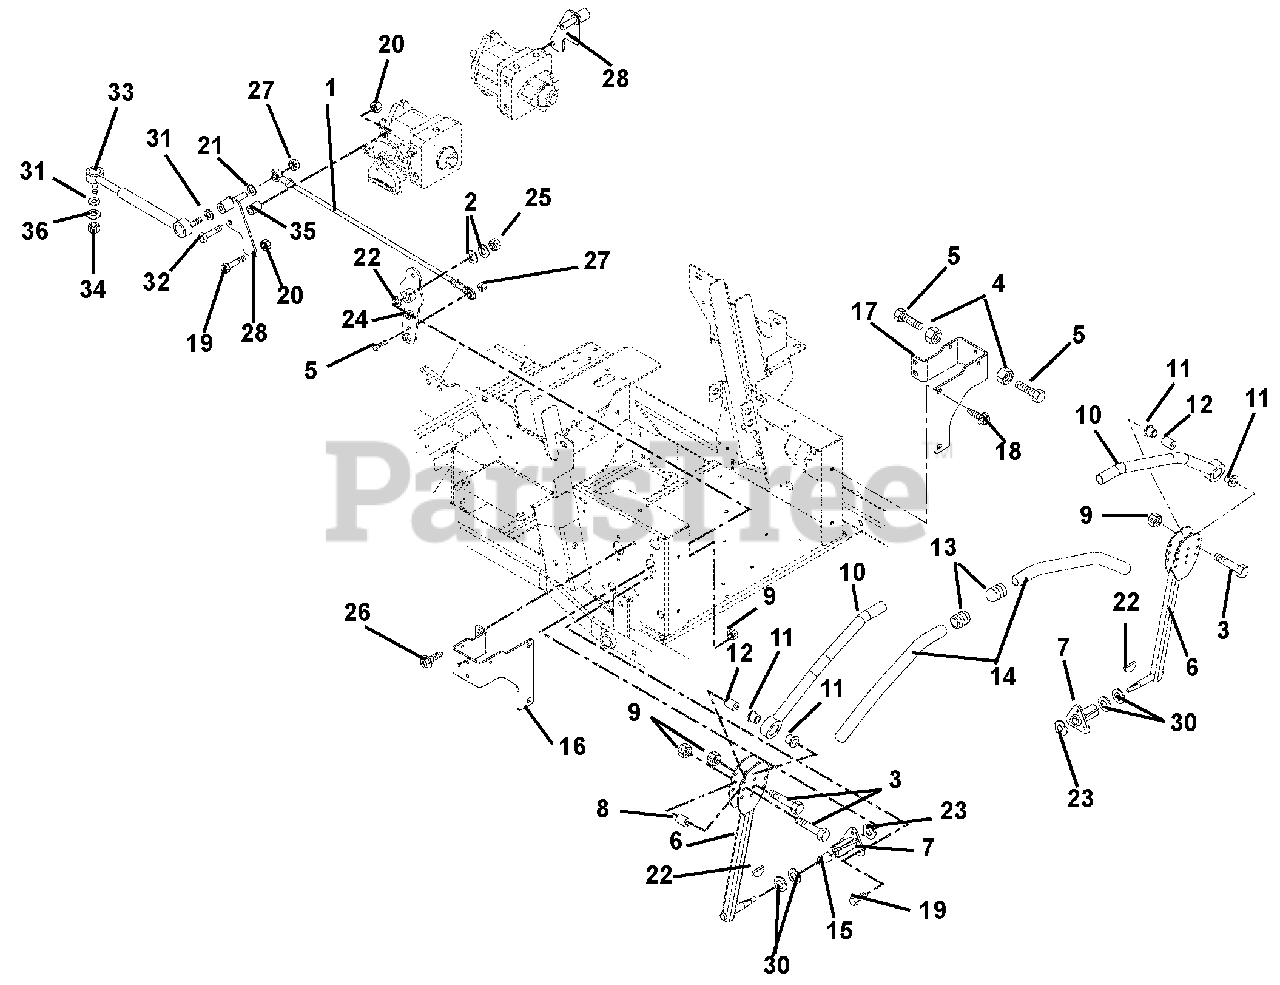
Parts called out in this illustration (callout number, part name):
1	ASSY,STEERING ROD .38RODX21.65
2	@WSHR-FL-STL.406X.812X.065 YWZ
3	@BLT-HEX .31-18X1.75 GR5 YWZC
4	NUT-HEX-JAM .375-16 YWZC
5	BLT-HEX .375-16X1.750 FTD YWZC
6	CONTROL ARM WELDMENT - BLACK
7	BUSHING, FLANGE
8	ECCENTRIC
9	@NUT-LK-TOP-FLG .31-18 YWZC
10	HANDLE WLDMT LH
11	BSHG-FLG .762X1.48X.44 NYL
12	SPACER .328 X .76 X 1.01
13	CAPLUG - HANDLEBAR
14	GRIP - HANDLEBAR
15	BSHG .625X.750X.500
16	RH STOP BRACKET - BLACK
17	LH STOP BRACKET - BLACK
18	@SCR-TAP .38-16X.75 HWH TR YWZ
19	@BLT-HEX .31-18X.75 GR5 YWZC
20	@NUT-LK-TOP-FLG .31-18 YWZC
21	@WSHR-LK .38X.094 REG YWZC
22	KEY-WDRF .13X.63 HRD#5
23	WAVE WASHER .640X.875X.125FH
24	WMT, PIVOT ARM
25	@NUT-LK-TOP-FLG .38-16 YWZC
26	@SCR-TAP .38-16X.50 HWH TR YWZ
27	@NUT-LK-CTR-JAM .375-16 YWZC
28	WMT, RTN/DAMPER/ROD END
29	@BLT-HEX .38-16X1.25 GR5 YWZC
30	WSHR-FL-STL .630X1.005X.062 YZ
31	@WSHR-LK .31X.078 REG YWZC
32	@BLT-HEX .31-18X1.25 GR5 YWZC
33	DAMPENER
34	@NUT-LK-NYL M8-1.25 YWZC
35	SPACER .318X.430X.375
36	@WSHR-FL-STL.38X.875X.083 YWZC
